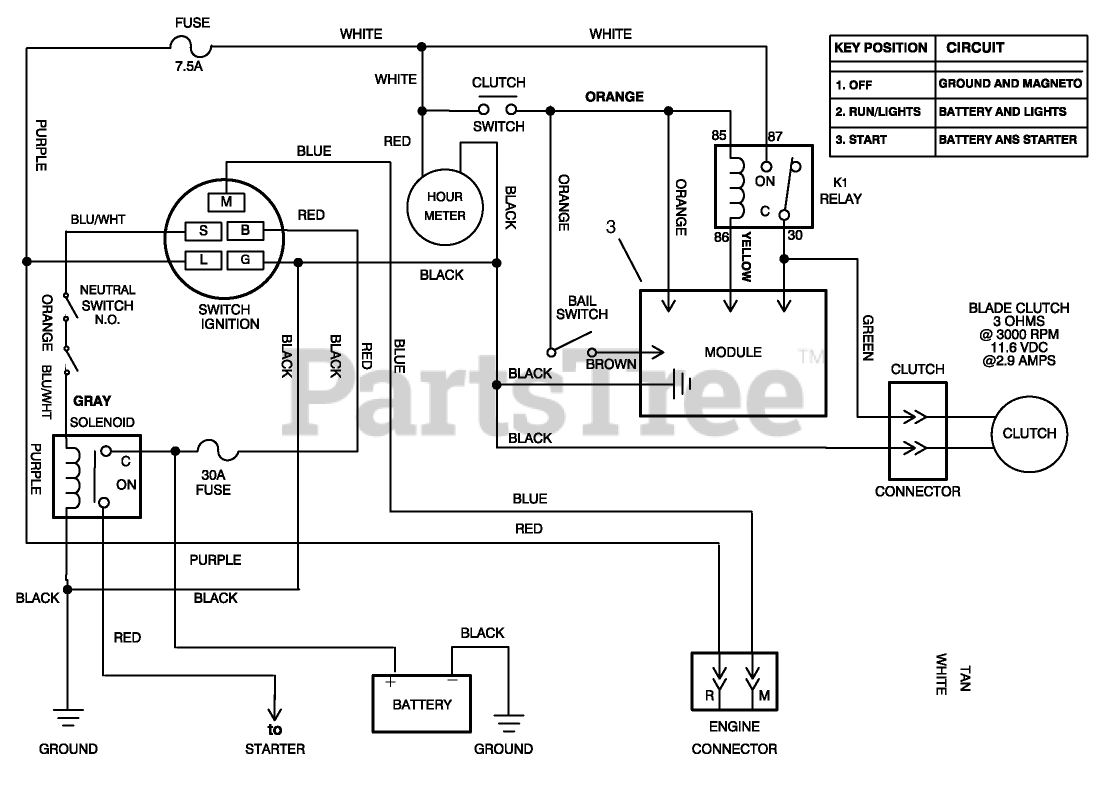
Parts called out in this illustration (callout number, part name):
1	HARNESS - WIRE
2	RELAY
3	MODULE
